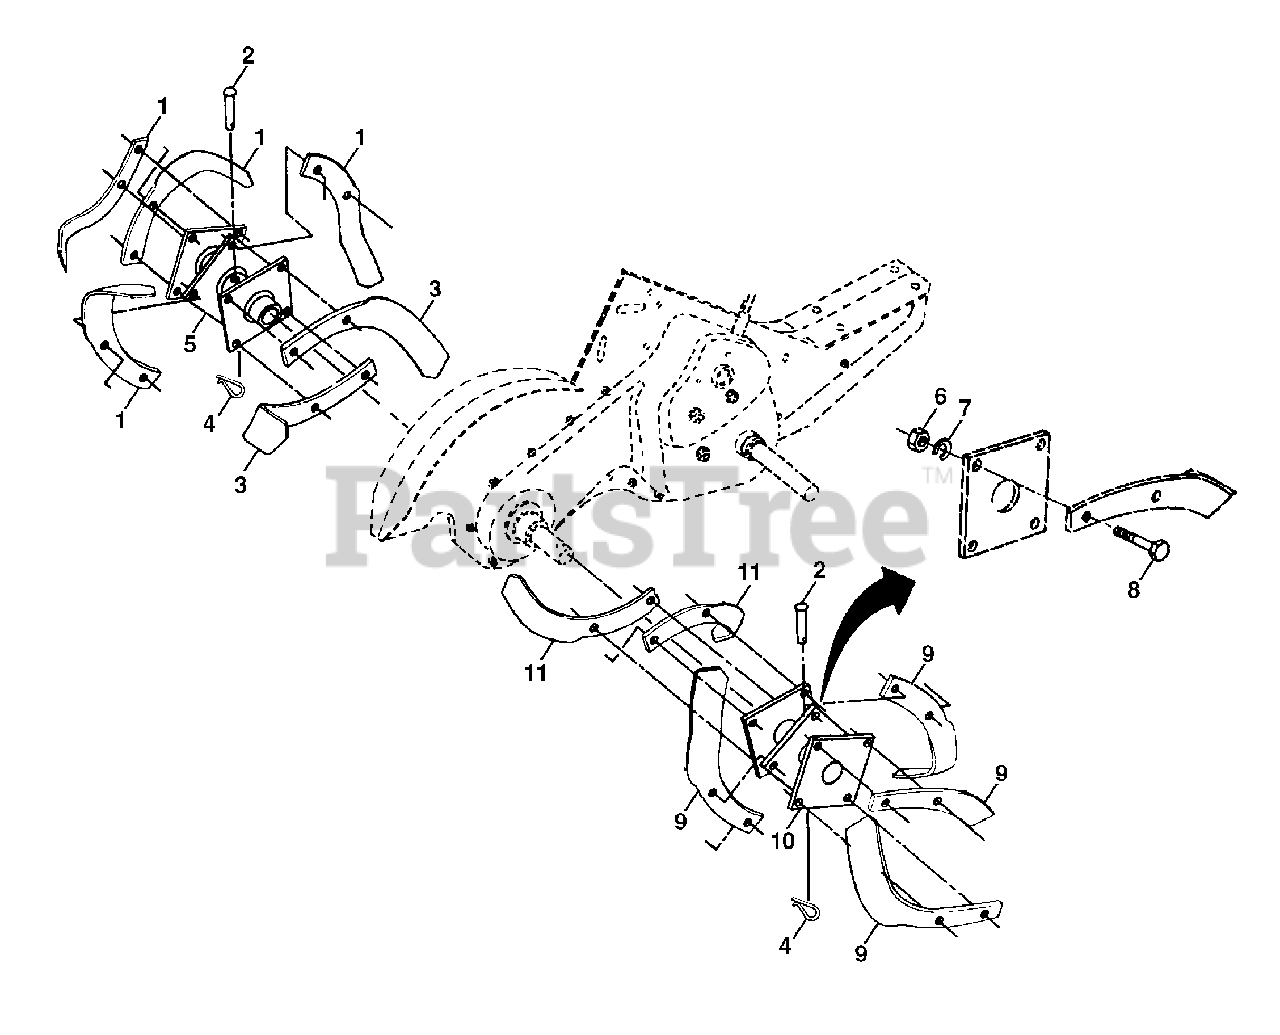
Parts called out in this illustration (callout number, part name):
1	Tine, Outer, L.H.
2	Clevis Pin
3	Tine, Inner, L.H.
4	Retainer Spring
5	Assembly, Hub and Plate, L.H.
6	Nut, Hex 3/8-24
7	Washer, Lock 3/8
8	Bolt, Hex 3/8-24 x 1
9	Tine, Outer, R.H.
10	Assembly, Hub and Plate, R.H.
11	Tine, Inner, R.H.
